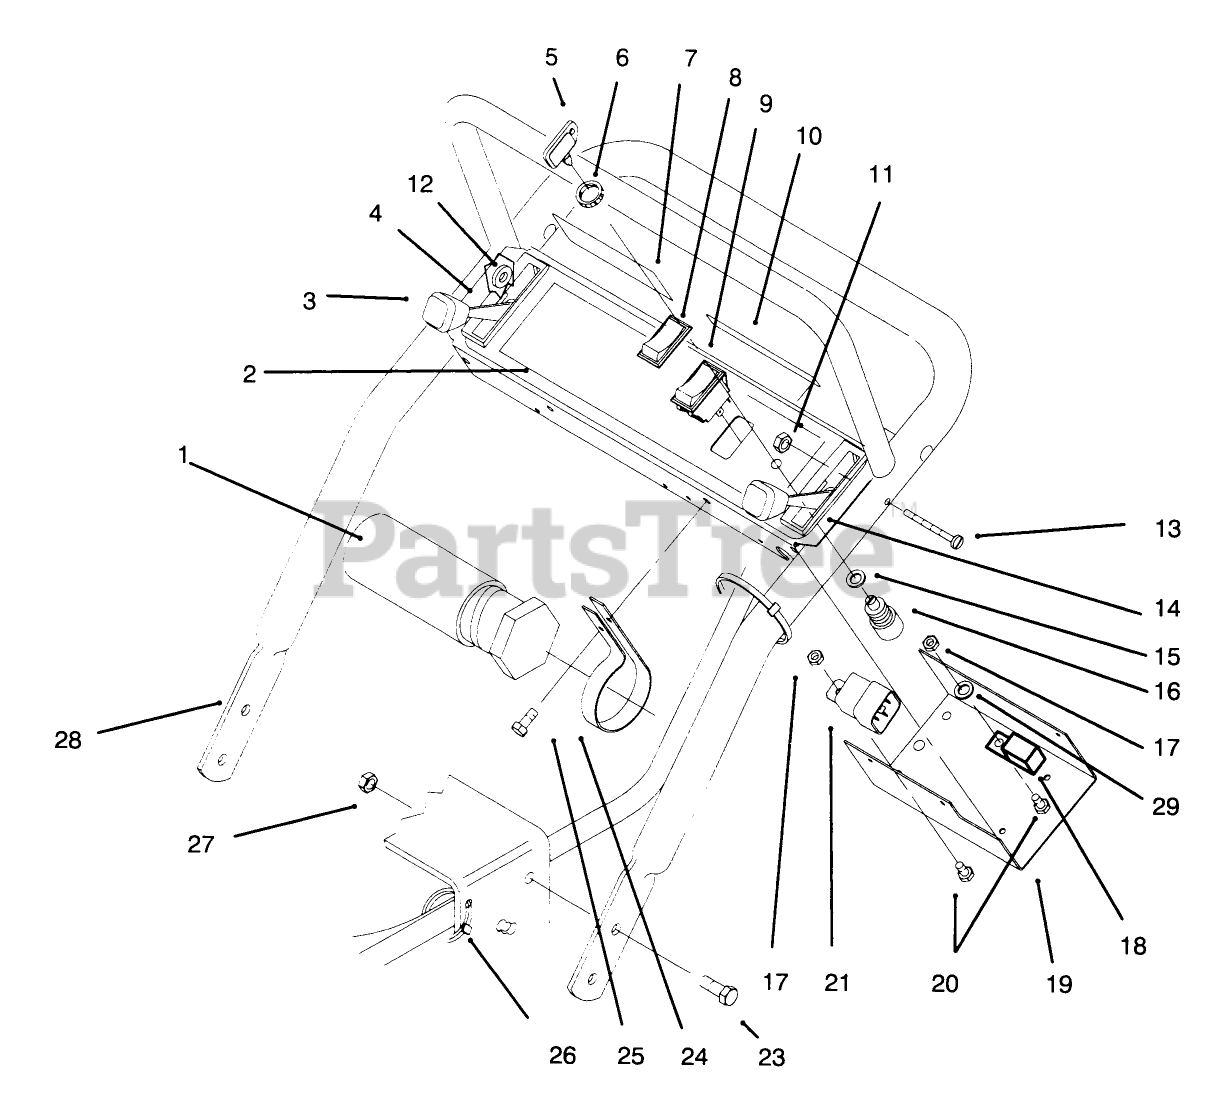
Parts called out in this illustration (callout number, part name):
1	TUBE-MANUAL
2	DECAL - CONTROL PANEL
3	CHOKE CONTROL
5	KEY-IGNITION
6	NUT-HH
7	DECAL-INSTRUCTION
8	BOOT-SWITCH
10	DECAL-DANGER
11	NUT-LOCK, NI
12	SPACER
13	SCREW-SHH
14	CONTROL - THROTTLE
15	WASHER-LOCK
16	SWITCH-STARTER
17	NUT-LOCK, NI
20	SCREW-HH
21	RELAY
23	SCREW-HHF
24	CLAMP-R
25	SCREW-SHWH
26	TIE-CABLE
27	NUT-HF
29	WASHER-LOCK/EXT
